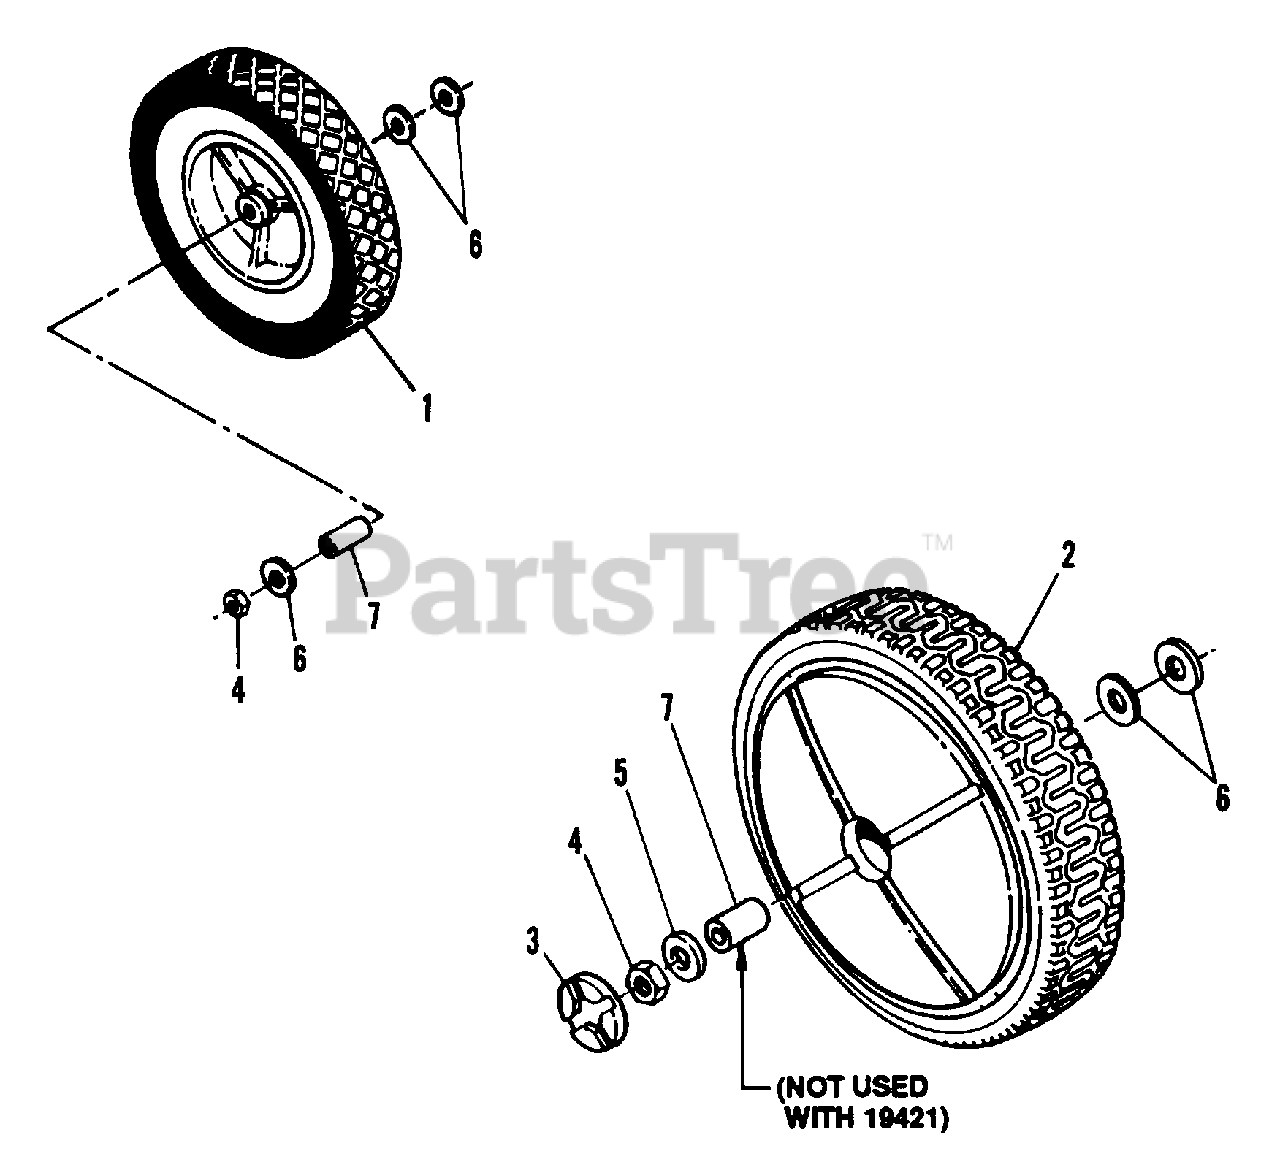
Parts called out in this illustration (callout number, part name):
1	WHEEL, 9 x 1.75 Plastic
2	WHEEL, 9 x 2.00 Plastic
3	PLUG, Wheel
4	NUT, 7/16-20 Hex (Thin)
5	WASHER, 7/16 x 7/8" O.D. Flat
6	WASHER, 7/16 x 1" O.D. Flat
7	BUSHING, Axle
